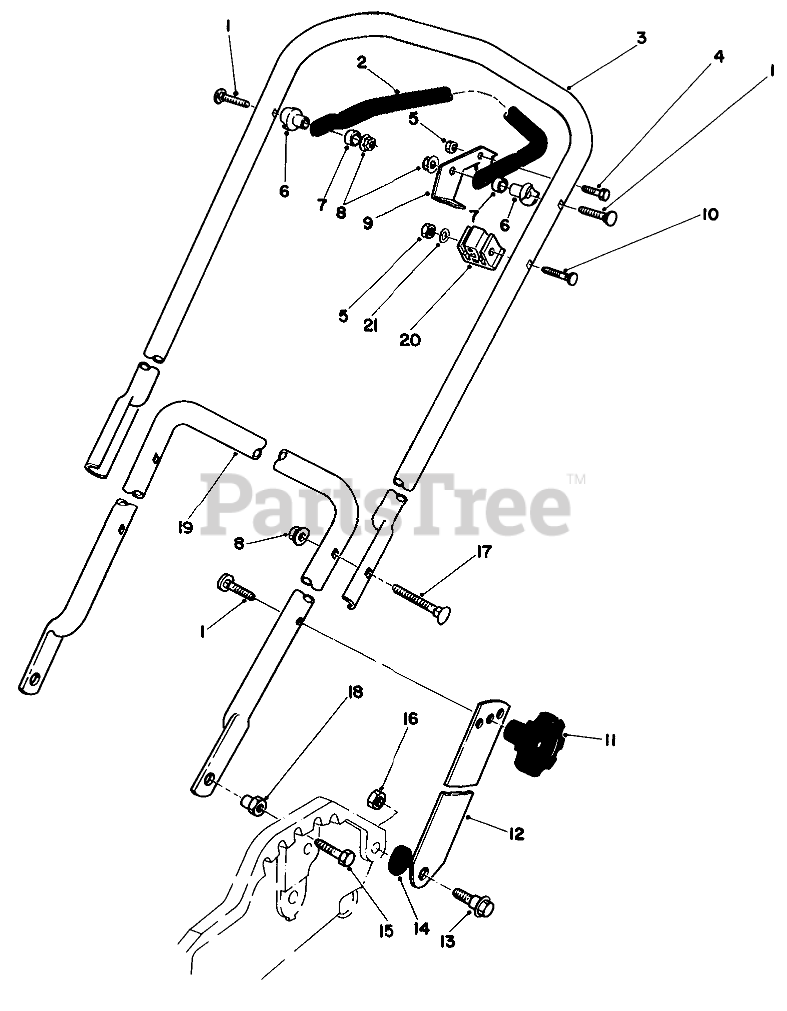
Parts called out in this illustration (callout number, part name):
1	5/16-18 X 2 HNDLE SCREW
2	CONTROL BAR
3	UPPER HANDLE
4	SCREW-HH
5	NUT-LOCK, NI
6	SPACER-SUPPORT
7	SPACER-NYLON
8	NUT-LOCK, NI
9	Lever-Control
10	HANDLE SCREW
12	Handle Latch
13	SCREW-SHOULDER
14	SPACER
15	SCREW-HH
16	NUT-LOCK, NI
17	SCREW
18	HANDLE PIVOT NUT
19	LOWER HANDLE
20	SUPPORT-CABLE
21	WASHER-FLAT
